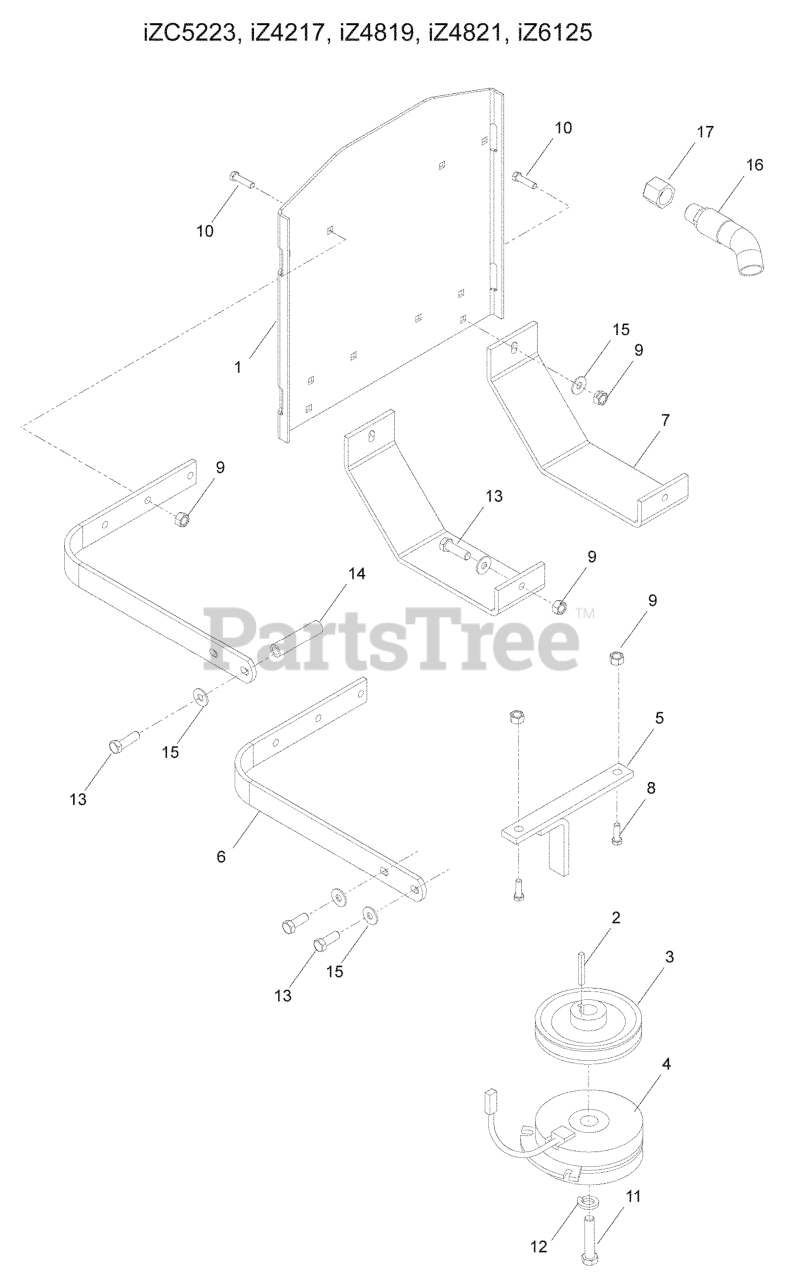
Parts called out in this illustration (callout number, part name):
1	ENGINE GUARD
2	KEY, 1/4 SQ X 1 1/4
4	ELECTRIC CLUTCH W/CABLE
5	CLUTCH TIE DOWN
6	ENGINE SHROUD BRKT
7	SKID PLATE
8	HCS 5/16C X 1 3/4
9	NUT 5/16 NYLOC
10	RHSSNB 5/16C X 1.0
11	BOLT 7/16F X 2 1/2
12	WASHER 7/16 LOCK
13	HCS 5/16C X 1
15	WASHER 5/16 FLAT
16	OIL DRAIN HOSE
